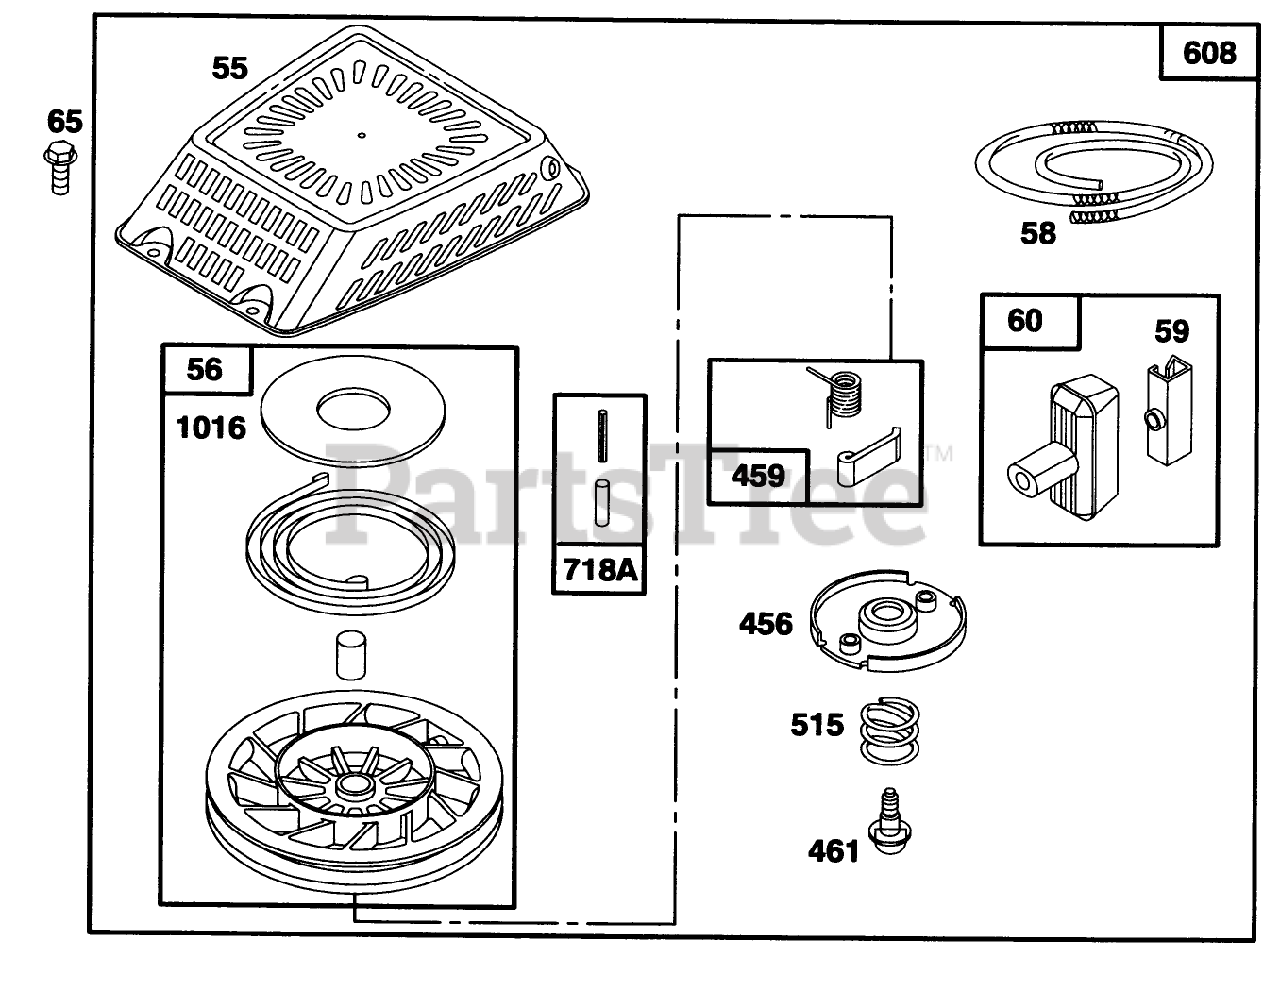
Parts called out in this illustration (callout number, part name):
59	INSERT-HANDLE, REWIND
456	RETAINER - SPRING
515	0 Spring-Torsion
